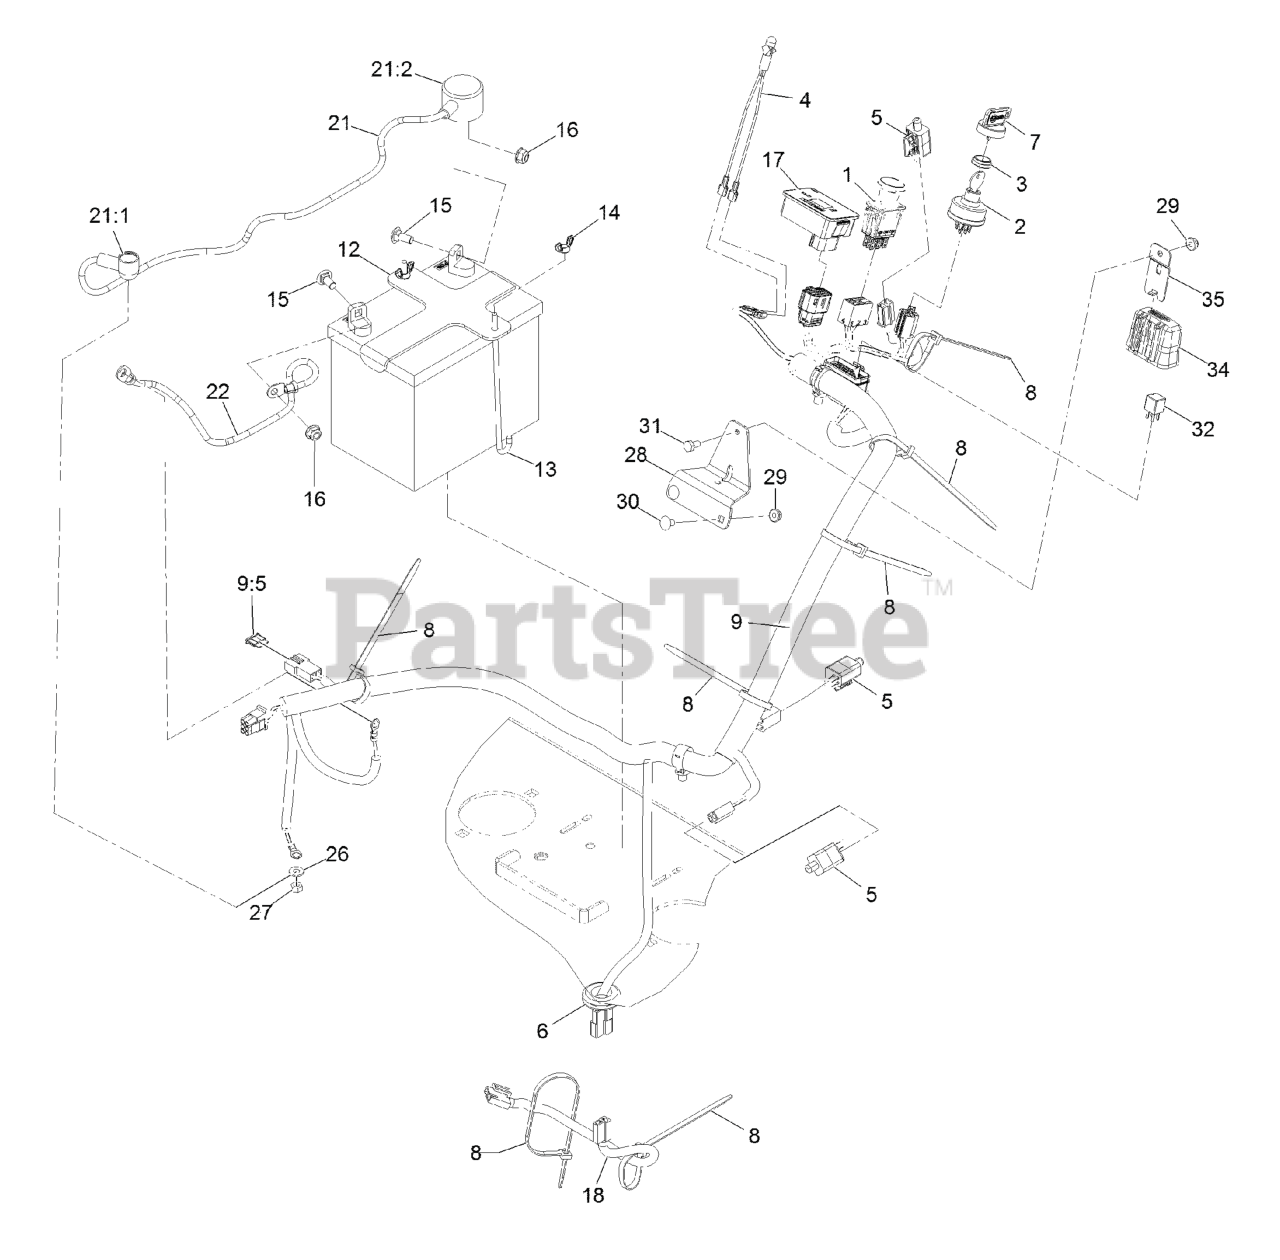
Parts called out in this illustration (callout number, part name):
1	SWITCH-PTO
2	SWITCH, KEY START
3	NUT-SWITCH, IGNITION
4	INDICATOR-LED, RED
6	GROMMET
7	KEY-IGNITION
8	TIE-PLASTIC
9	HARNESS-WIRE
9:5	FUSE-BLADE TYPE, 20 AMP
12	BRACKET, BATTERY HOLD DOW
13	BOLT-HOLDDOWN
14	WINGNUT
15	BOLT-CARR
16	NUT-HF, NI
17	MODULE-HOUR METER
18	HARNESS-CLUTCH PIGTAIL
21	POSITIVE BATTERY CABLE AS
21:1	INSULATOR-SOLENOID
21:2	INSULATOR-BATTERY
26	WASHER-FLAT
27	NUT-HEX
28	BRACKET-MOUNTING, FUSEBLO
30	SCREW-CARR
31	SCREW-HH
32	RELAY-MICRO
34	COVER-BLOCK, FUSE
35	CLIP-MOUNTING
